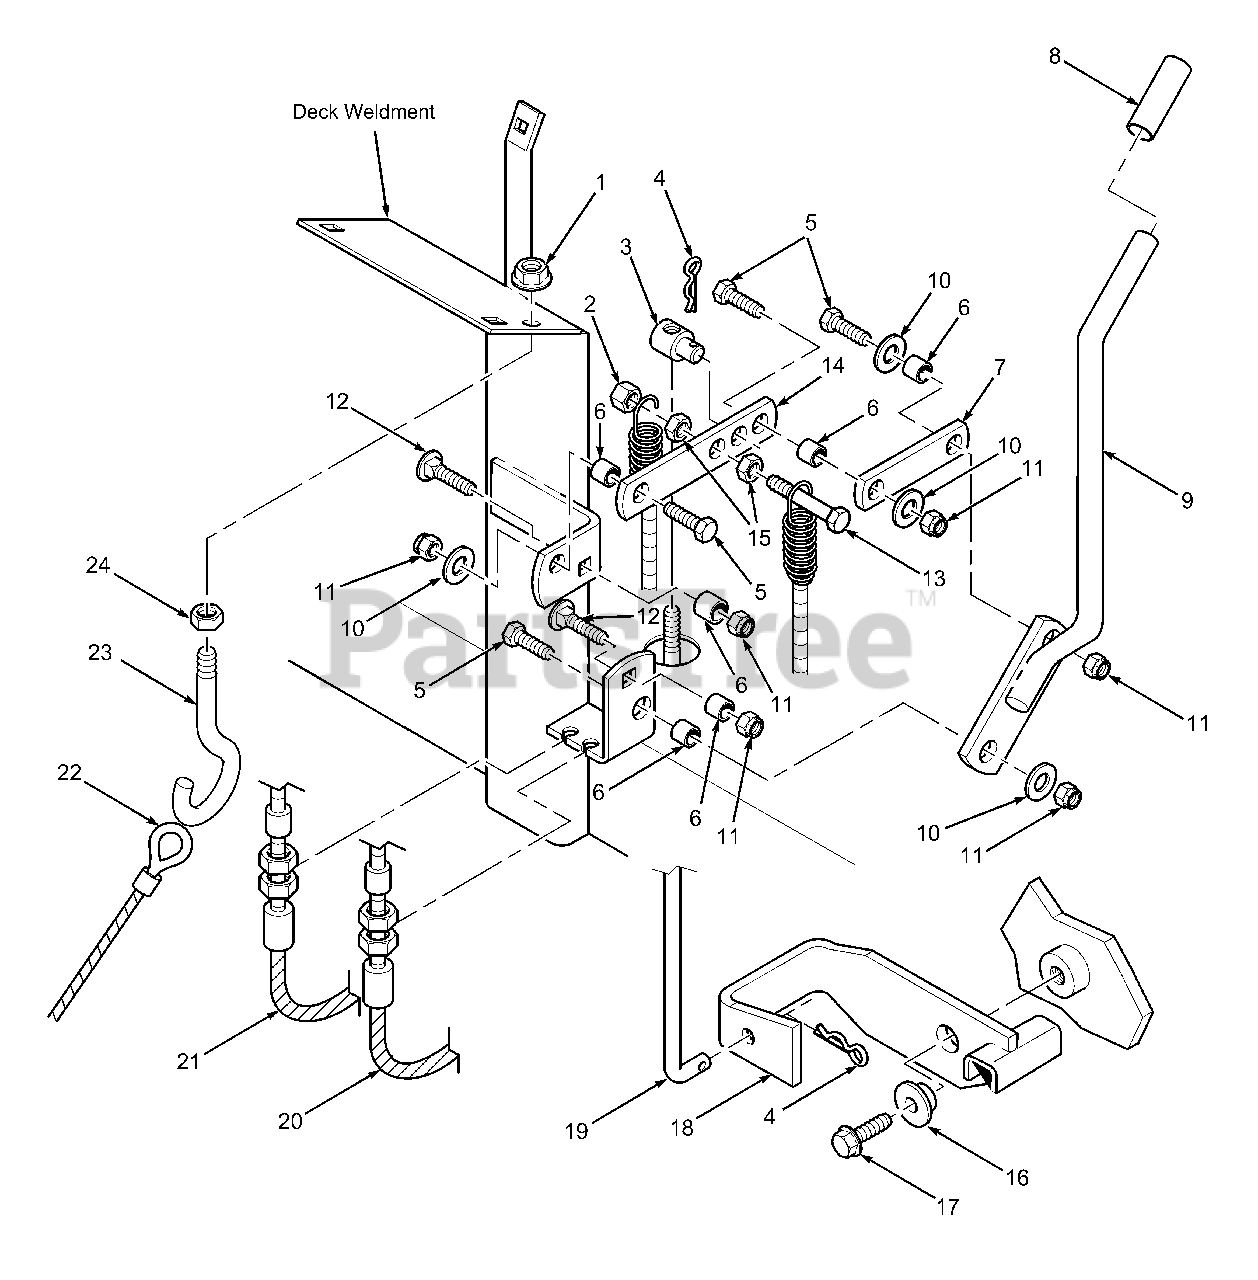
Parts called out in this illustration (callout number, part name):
1	Serr. Fl. HH Nut, 3/8-16
2	Hex Locknut, 3/8-16
3	Swivel
4	Hairpin Cotter (.094 x 1.62)
5	Hex Head Bolt, 3/8-16 x 1-1/4"
6	Sleeve, Hydro Linkage
7	Link, Cam
8	Grip, Parking Brake
9	Handle, Parking Brake
10	Flat Washer, 3/8 (.391 x .938 x .105)
11	Hex Nut, Elastic Stop 3/8-16
12	Carriage Bolt, 3/8-16 x 1-1/4"
13	Hex Head Bolt, 3/8-16 x 1-3/4"
14	Lever, Brake
15	Hex Jam Nut, 3/8-16
16	Washer, Neutral Lock
17	Serr. Fl. HH CPSCR, 3/8-16 x 1"
18	Bracket, Neutral Lock
19	Rod, Neutral Lock
20	Cable Assembly, Parking Brake R.H.
21	Cable Assembly, Parking Brake L.H.
22	Cable Winch
23	Eye Bolt, 3/8-16 R.H.
24	Hex Nut, 3/8-16
